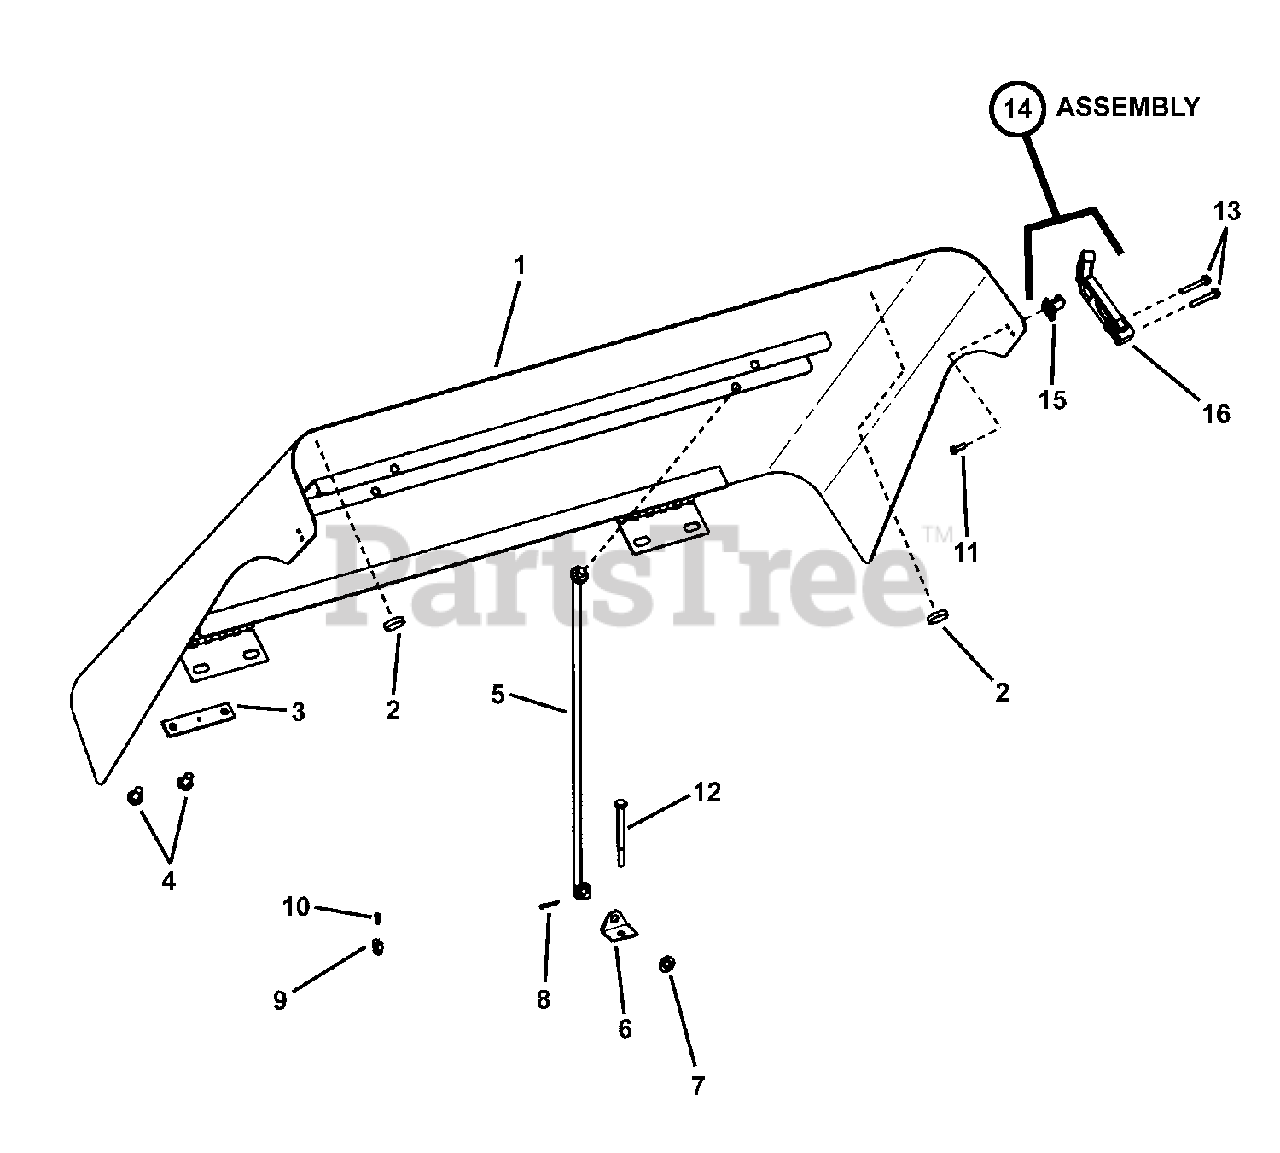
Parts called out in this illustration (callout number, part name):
1	WELDMENT, Hood (Red)
1	WELDMENT, Hood (Green)
2	HOOD PAD
3	PLATE WASHER
4	SCREW 5/16-18 x 5/8" Cross Recessed Pan Head
5	HOOD PROP
6	BRACKET, Hood Prop
7	WASHER, .34 x .69 x .08 Flat
8	COTTER PIN, 3/32 x 3/4"
9	HOLDER, Hood Prop
10	SCREW, #6-20 x .34 Pan Head Self-Tap
11	SCREW, #10-24 x 1/2" Pan Head Machine
12	SCREW, 1/4-20 x 3" Hex Head Cap, GR 5
13	SCREW, #10 x 1-1/4" Hex Washer Self-Tap, HI-LO
14	ASSY, Hood Latch (incl. Ref, Nos. 15 & 16)
15	KEEPER
16	ASSEMBLY, Hood Handle
